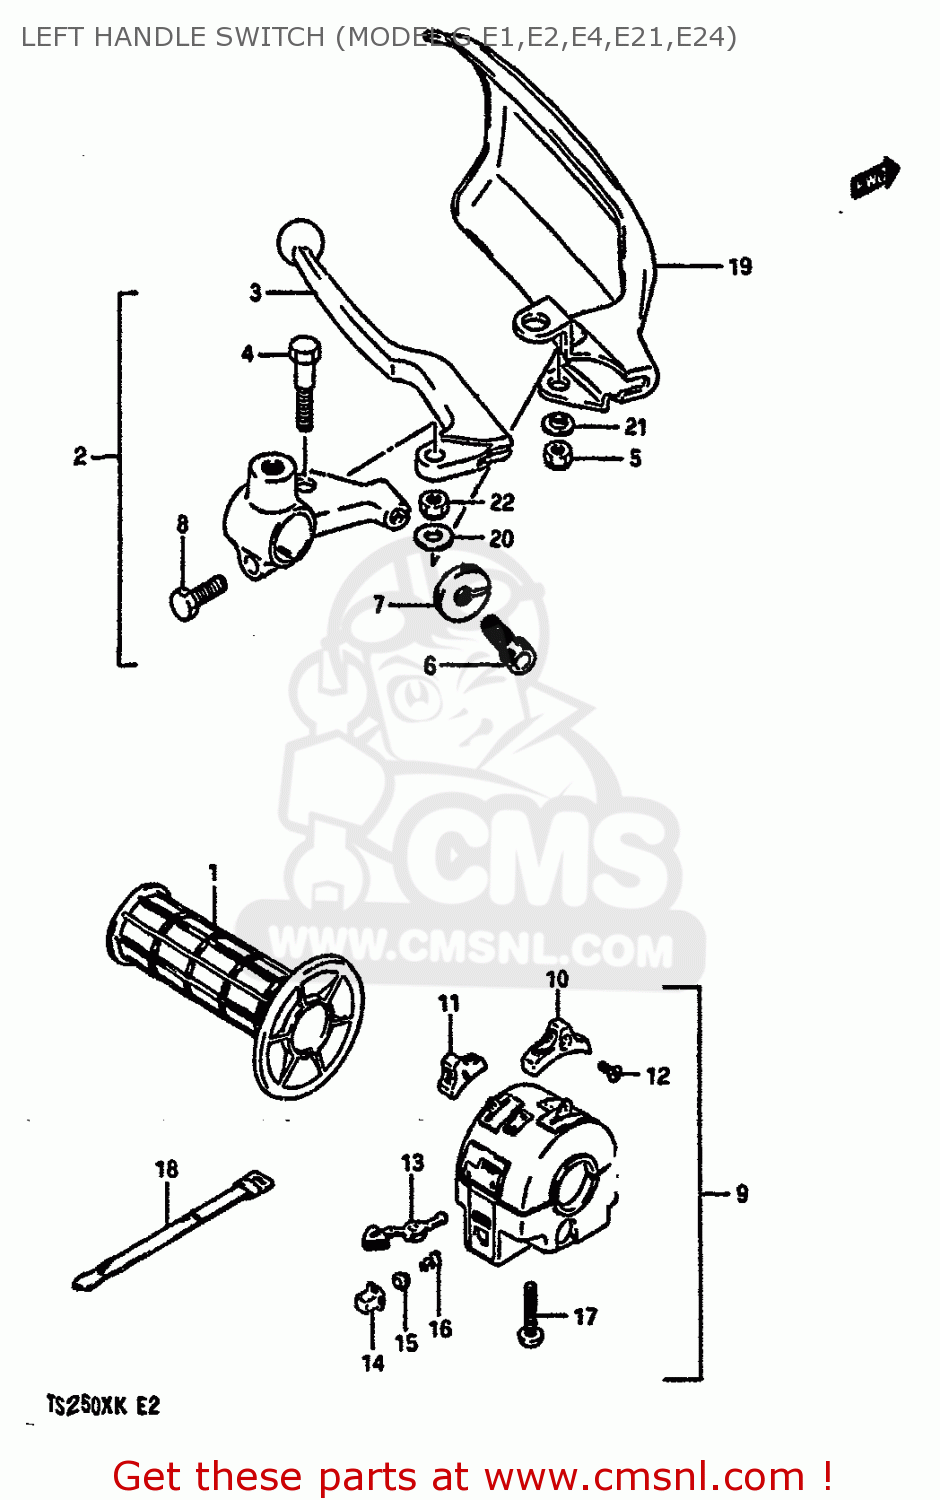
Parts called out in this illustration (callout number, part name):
1	GRIP,LEFT
2	LEVER, CLUTCH
3	LEVER,CLUTCH
4	BOLT,LEVER SET
5	NUT
6	ADJUSTER,CABLE
7	NUT,CABLE ADJUSTER LOCK
8	BOLT
9	SWITCH ASSY,HANDLE LH
10	KNOB,LIGHTING SWITCH
11	KNOB,DIMMER SWITCH
12	SCREW
13	KNOB,TURNSIGNAL
14	BUTTON,HORN
15	CONTACT
16	SPRING
17	SCREW
18	CLAMP(L:120)
19	COVER,KNUCKLE,LEFT
20	WASHER(6.5X16X1.2)
21	WASHER
22	NUT 6MM
